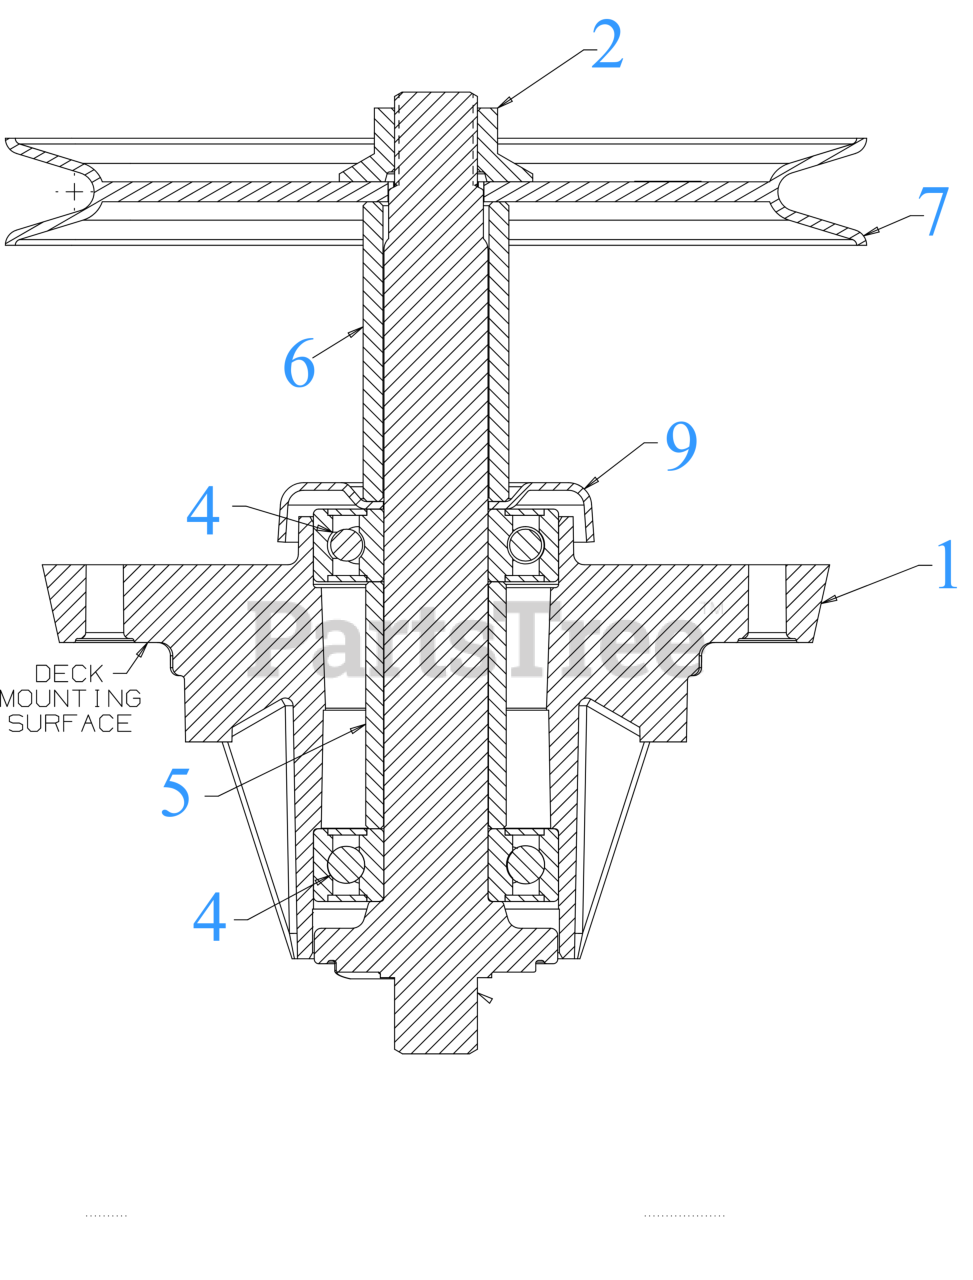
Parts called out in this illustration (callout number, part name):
1	DECK SPINDLE HOUSING
2	FLANGE NUT 5/8-18
4	BALL BEARING
5	SPACER- .792 x 1.060 x 1.860
6	SPACER .80 x 1.10 x 2.26 LG
7	DECK PULLEY 6.93"
9	SHIELD-BRG DECK
